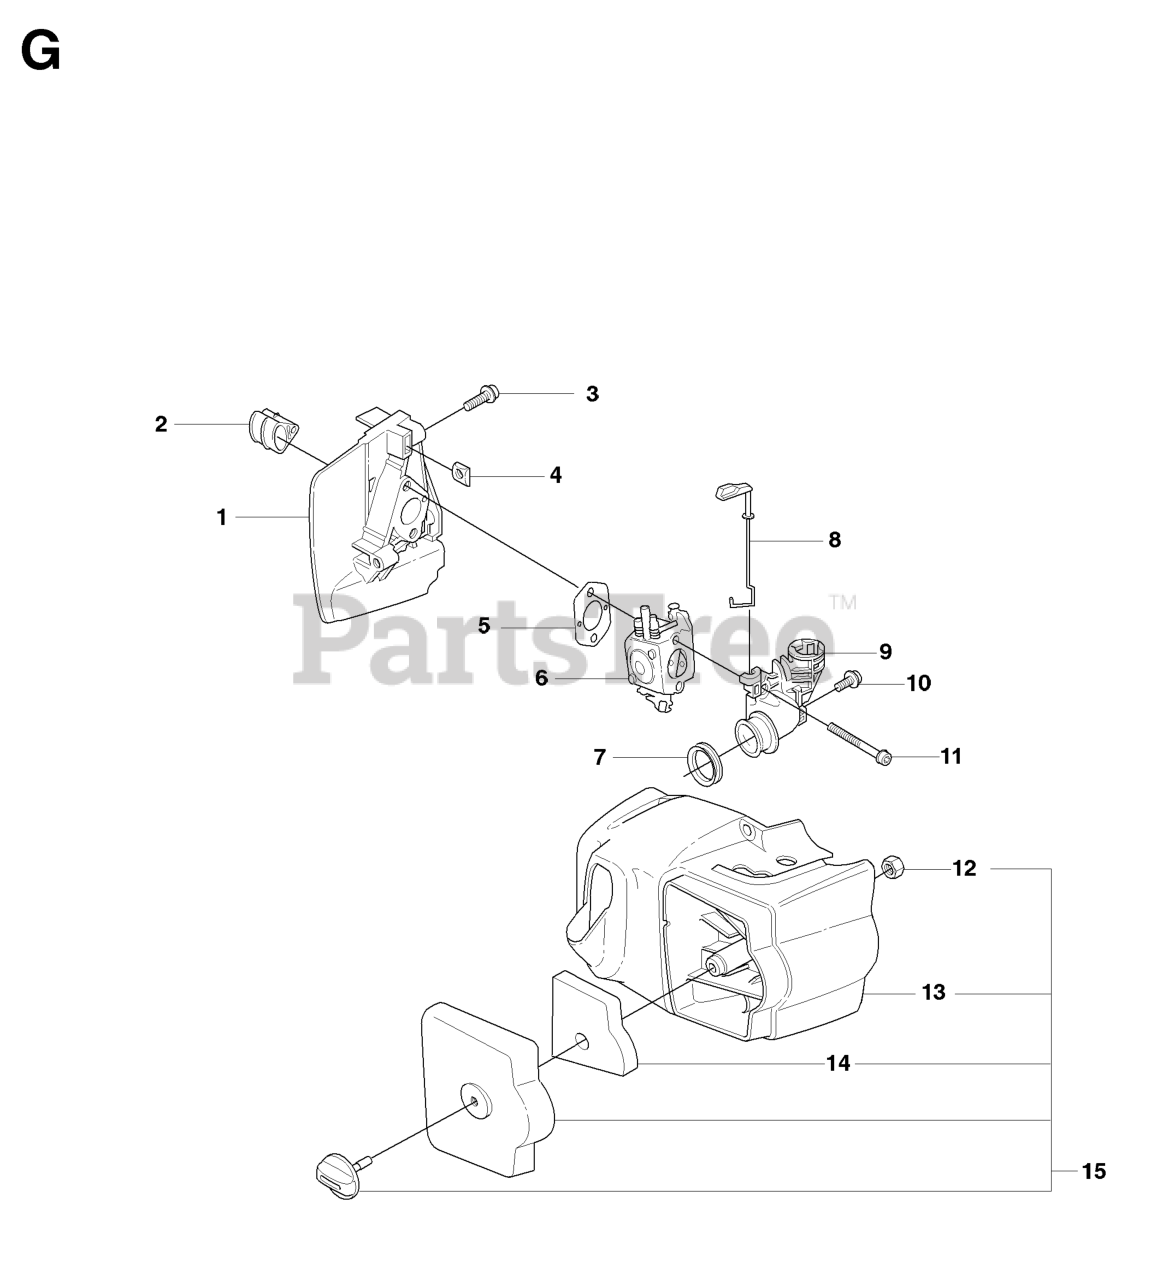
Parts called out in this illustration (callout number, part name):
3	SCREW
6	CARBURETOR
8	CHOKE CONTROL
13	CYLINDER COVER
14	AIR FILTER
15	CYLINDER COVER ASSY 326
